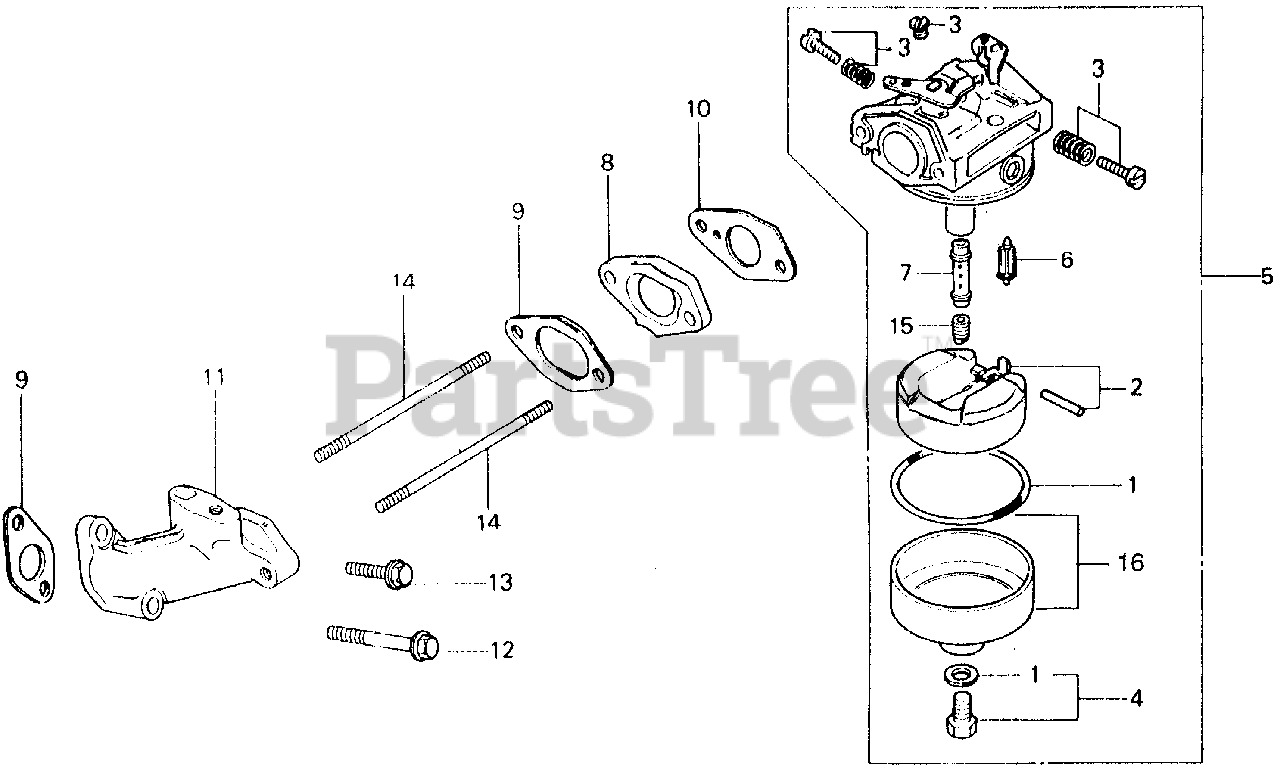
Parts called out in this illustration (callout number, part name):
1	GASKET SET
2	FLOAT SET
3	SCREW SET A
3	SCREW SET A (CARBURETOR NO.) (NOT AVAILABLE)
4	SCREW SET B
5	CARBURETOR ASSY.
6	VALVE, FLOAT
7	NOZZLE, MAIN
15	JET, MAIN (#60) (Honda Code 0635474). (CARBURETOR NO.)
15	JET, MAIN (#62) (Honda Code 0635482). (CARBURETOR NO.)
15	JET, MAIN (#65) Use up to Engine SN BB30A D.
16	CHAMBER SET, FLOAT
